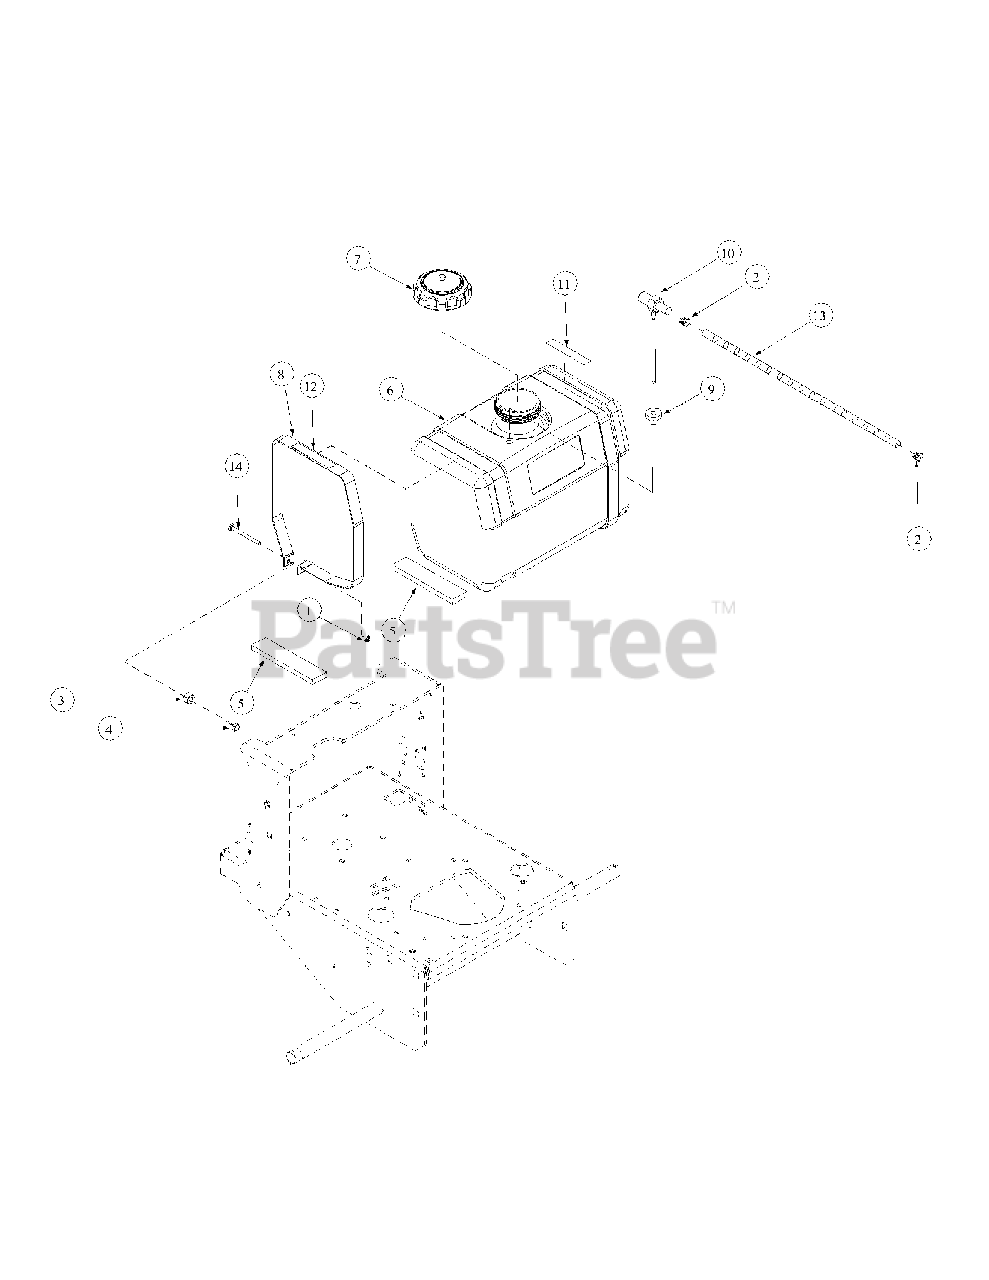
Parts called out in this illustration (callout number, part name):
1	Lock Nut, Nylon Insert, 1/4-20
2	Uni-Clamp
4	Nut, 1/4-20
5	Rubber Stop Pad
6	Fuel Tank
7	Fuel Cap, 3.5
8	Fuel Tank Strap
9	Grommet Fuel Tank
10	Shut Off Fuel Tank
11	Label, Mower Warning Turn Off Engine
12	Label, Mower Instruction, Fuel Valve
13	Hose Fuel, 22" x .25 ID
14	Carriage Bolt, 1/4-20 x 3.00
